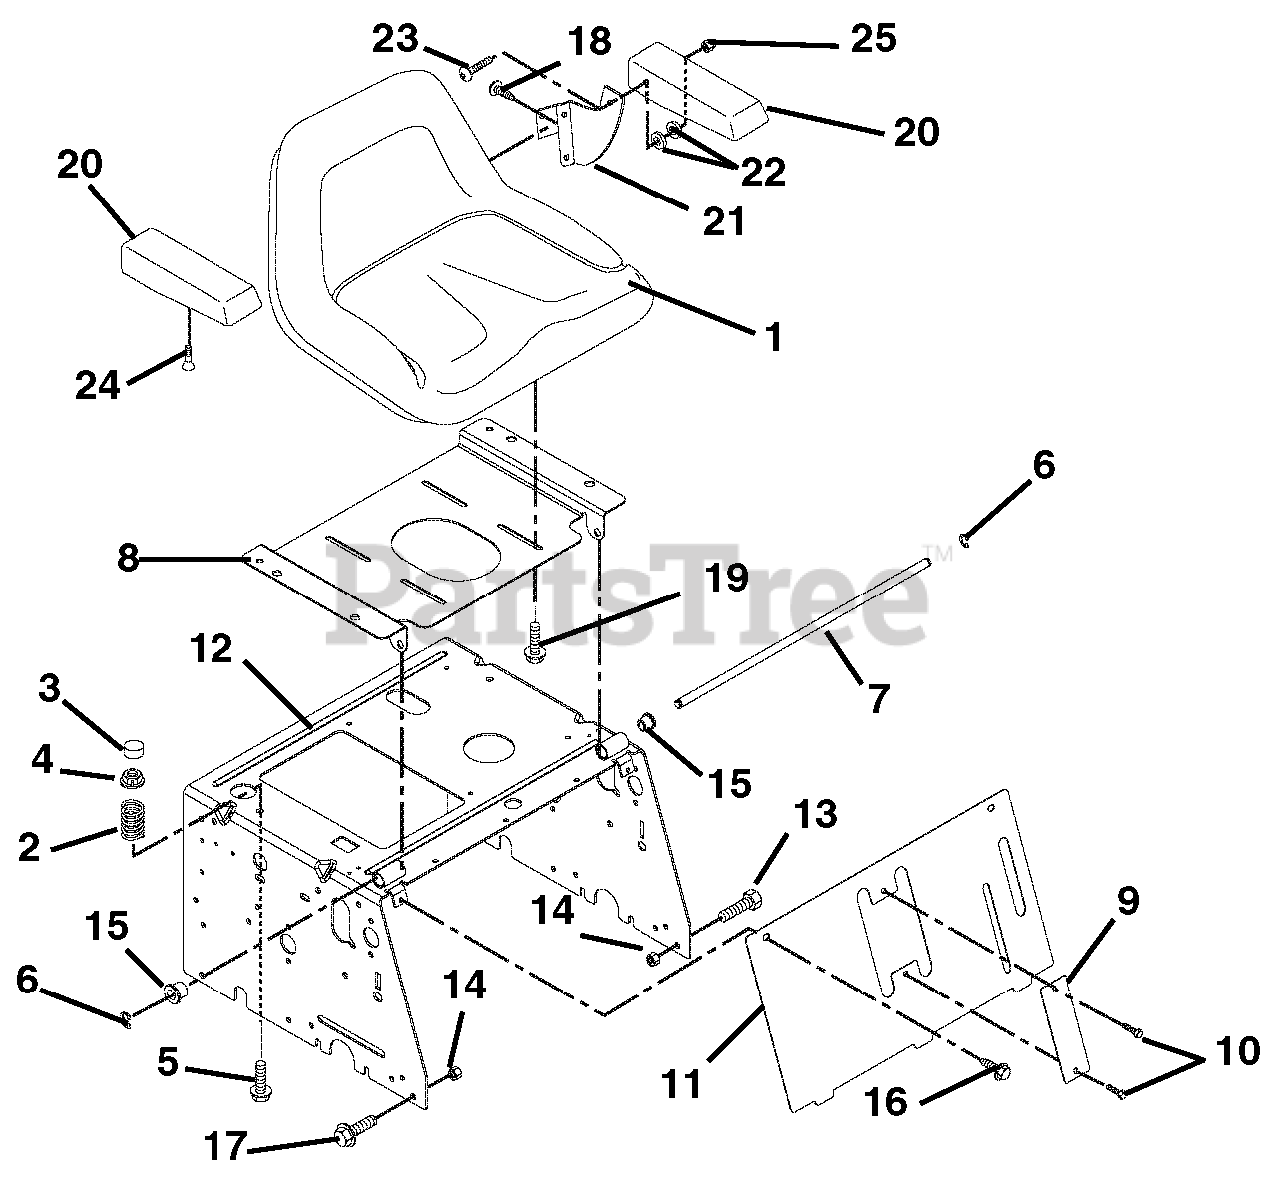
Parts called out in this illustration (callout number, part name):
2	Spring-Compression 2.9L x 2.02 OD
3	Boot-Seat Spring
4	Nut-Locking, Flange .375-16
5	Bolt-Hex Flanged Whiz Lock Head .38-16 x .75
6	Ring-Retaining-External .500 x .042
7	Axle-Front
8	Plate-Seat
10	Bolt-Hex .25-20 x .50 Grade 5
11	Panel-Weldment
12	Support-Seat Weldment
13	Bolt-Screw Hex Flanged Whiz Lock Head .38-16 x .75
14	Nut-Locking-Top-Flange .38-16
15	Bushing-Flange
16	Screw, Tapping .31-18 x .75
17	Bolt-Serrated Hex Flange Washer Head .38-16 x 1.00
18	Screw-Round Head Socket Tapping .31-18 x .62 Grade 8
19	Bolt Serrated Hex Flange Washer Head .31-18 x .62 Grade 5
20	Arm Rest
21	Bracket-Left Hand Armrest
21	Bracket-Right Hand Armrest
23	Bolt, Round Head Socket .38-16 x 1.50 Grade 8
24	Bolt-Socket Flat Head .38-16 x .50
25	Nut, .38-16 Low Crown Lock Acorn
